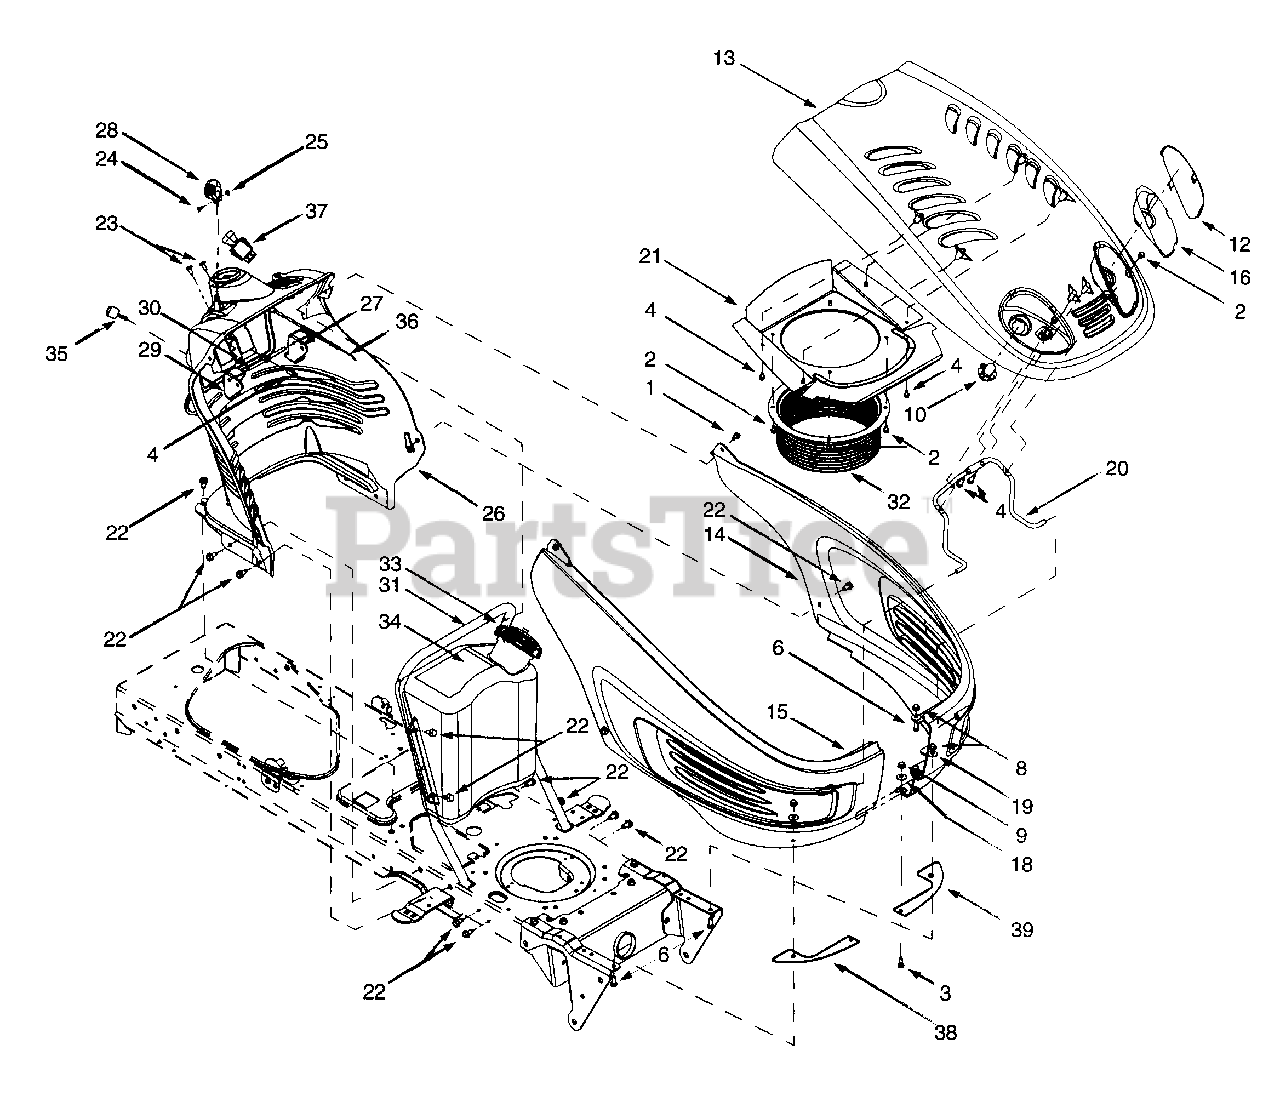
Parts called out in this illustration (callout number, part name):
1	Self Tapping Screw, 1/4-20 x 1.0
2	Self Tapping Screw, 1/4-20 x .5
3	Hex Cap Screw, 1/4-20 x .62
4	Self Tapping Screw, 1/4-15 x .75
6	Hex Cap Screw, 5/16-18 x .75
8	Flange Lock Nut, 5/16-18
9	Hex Flange Lock Nut, 1/4-20
10	Head Lamp Socket
12	LH Head Light Lens
13	Hood, 4-style (Yellow)
14	LH Side Panel, 4-style (Yellow)
15	RH Side Panel, 4-style (Yellow)
16	LH Head Light Reflector
18	Flat Washer, .28 x .74 x .063
19	Flat Washer, .349 x 1.0 x .063
20	Hood Support Rod
22	Self Tapping Screw, 5/16-18 x .625
23	Torx Self Tapping Screw, 1/4-14 x .625
24	Torx Screw, #8-32 x .375
25	Hex Nut, 8-32
26	Dash Panel, 4-style
27	Parking Brake Button
28	Throttle Control Lever
29	Cruise Control Button
30	Brake/Cruise Pivot Rod
33	Fuel Cap
34	Fuel Tank (Three Gallon)
35	Ignition Key
36	Choke Knob/Cable Assembly
37	Electric PTO Switch
38	RH Grill Heat Shield
39	LH Grill Heat Shield
